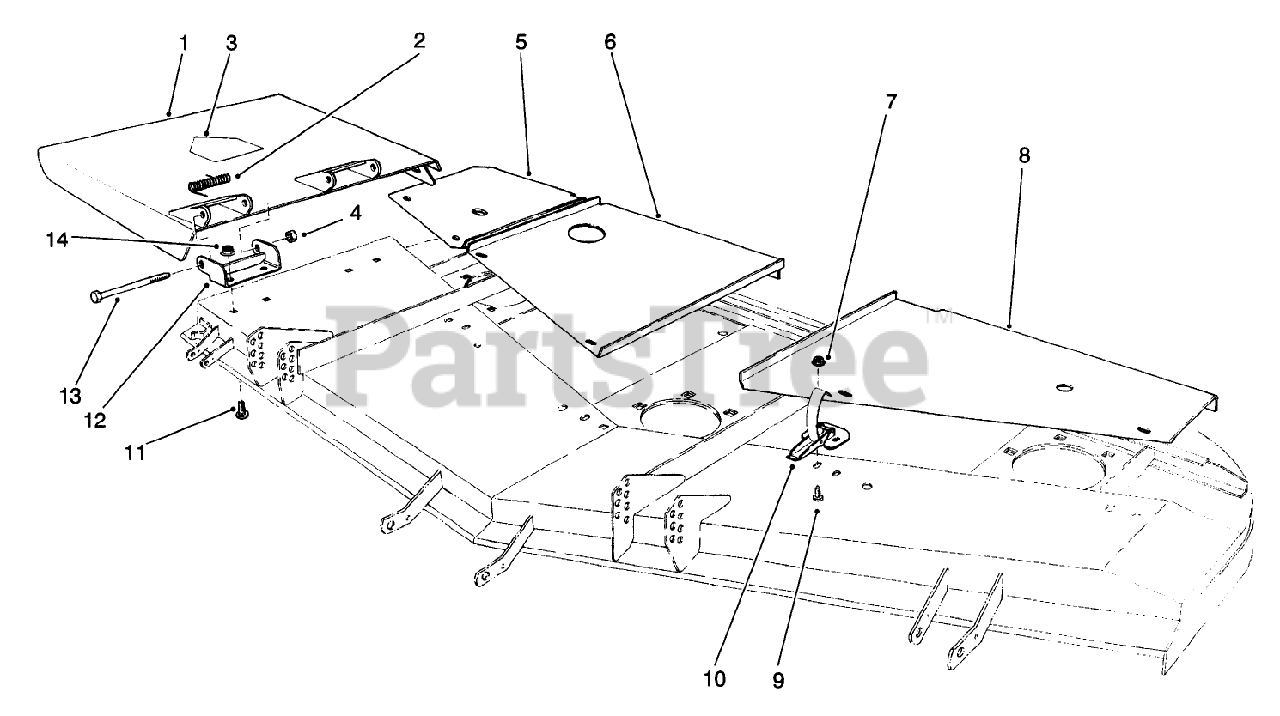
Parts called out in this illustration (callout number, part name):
1	Deflector Assembly (Incl. Ref. #3)
2	SPRING
3	DECAL-DANGER
4	NUT-HEX
5	Cover R.H.
6	Cover-Center
7	NUT-LOCK, FLANGE
8	Cover L.H
9	SCREW-HWH
10	CLAMP-SLOTTED
11	SCREW-CARR
12	Bracket-Hinge
13	SCREW-HH
14	NUT-HHF, WHIZ
